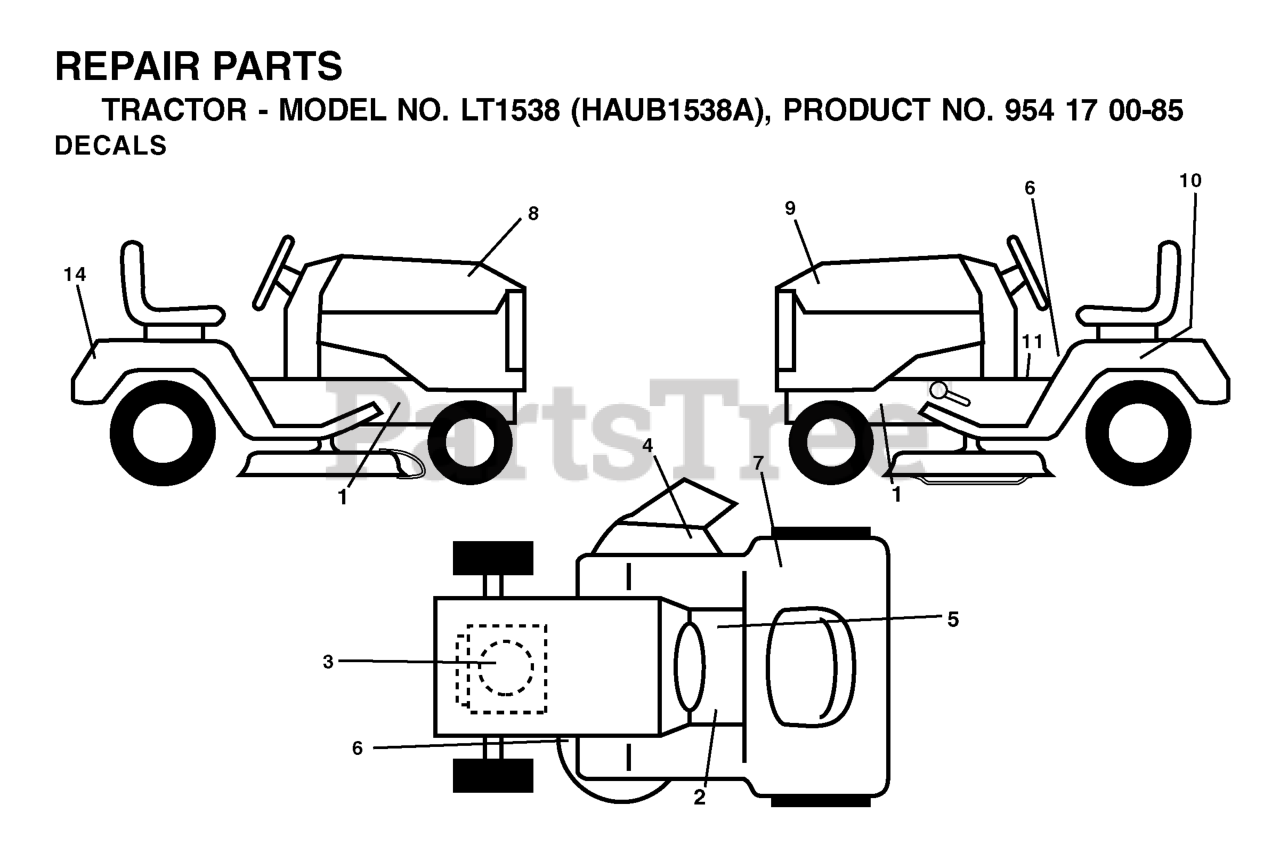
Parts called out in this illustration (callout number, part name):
2	DECAL
4	DECAL.INTERNATIONL.CUTFINGER
5	DECAL PARK BRAKE
6	DECAL V-BELT SCHEMATIC
7	DECAL
10	DECAL BTRY SYMBOLS
11	DECAL READ OWNER'S MAN SYMS
14	DECAL, FENDER
